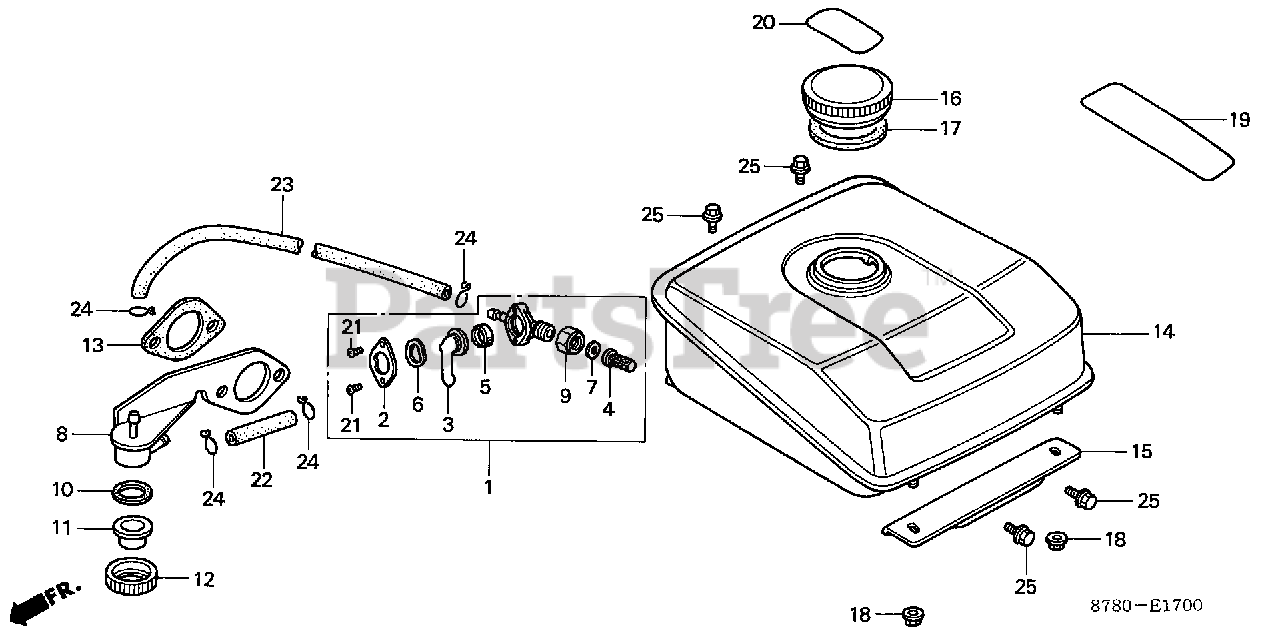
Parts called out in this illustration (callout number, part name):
1	PETCOCK ASSY. (NOT AVAILABLE)
2	COVER, PETCOCK (NOT AVAILABLE)
3	LEVER, PETCOCK (NOT AVAILABLE)
4	SCREEN, STRAINER
5	GASKET, PETCOCK VALVE
6	SPRING, PETCOCK LEVER
7	GASKET, FUEL STRAINER CUP (NOT AVAILABLE)
9	NUT, TURN BUCKLE (NOT AVAILABLE)
14	TANK, FUEL (NOT AVAILABLE)
15	STAY, FUEL TANK
16	CAP, FUEL FILLER
16	CAP, SUB-TANK
17	GASKET, FUEL FILLER CAP
18	NUT, FLANGE (6MM)
19	MARK A, CAUTION
21	SCREW, PAN (3X6)
23	BULK HOSE, FUEL (4.5X3000) (95001-450(95001-45001-60M)
23	BULK HOSE, FUEL (4.5X3000) (4.5X110)
24	CLIP, TUBE (B8)
25	BOLT, FLANGE (6X12)
